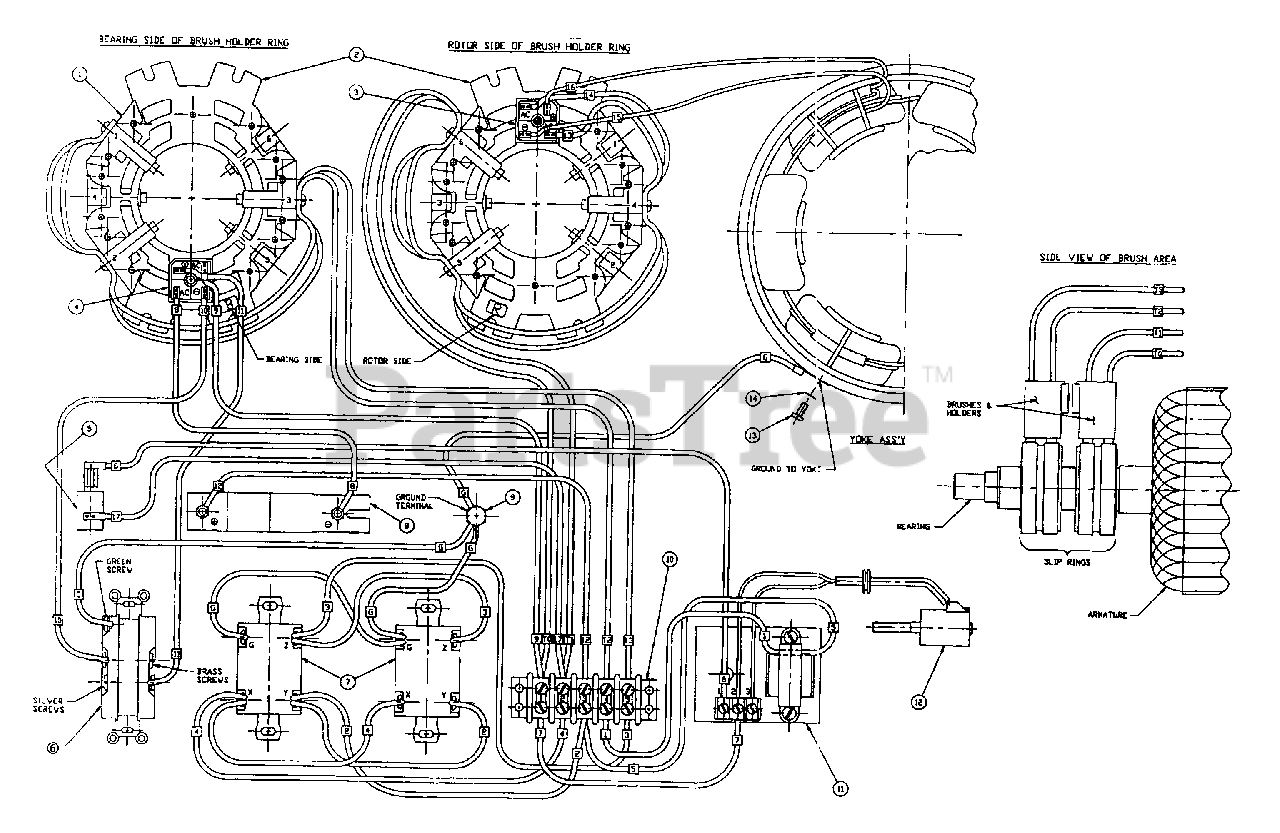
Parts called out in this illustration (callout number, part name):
1	BRUSH HOLDER
2	BRUSH HOLDER RING
3	RECTIFIER 35 AMP
4	RECTIFIER 40 AMP
6	DUPLEX RECEPTACLE
7	RECEPTACLE
8	CIRCUIT BREAKER
9	HEX HD CAP SCREW 5/16-16 X 1-1/4
10	TERMINAL BLOCK
11	IDLE CONTROL BOARD
12	ELECTRO MAGNET
13	PAN HD MACH SCREW 8-32 X 3/8
14	LOCK WASHER #08
